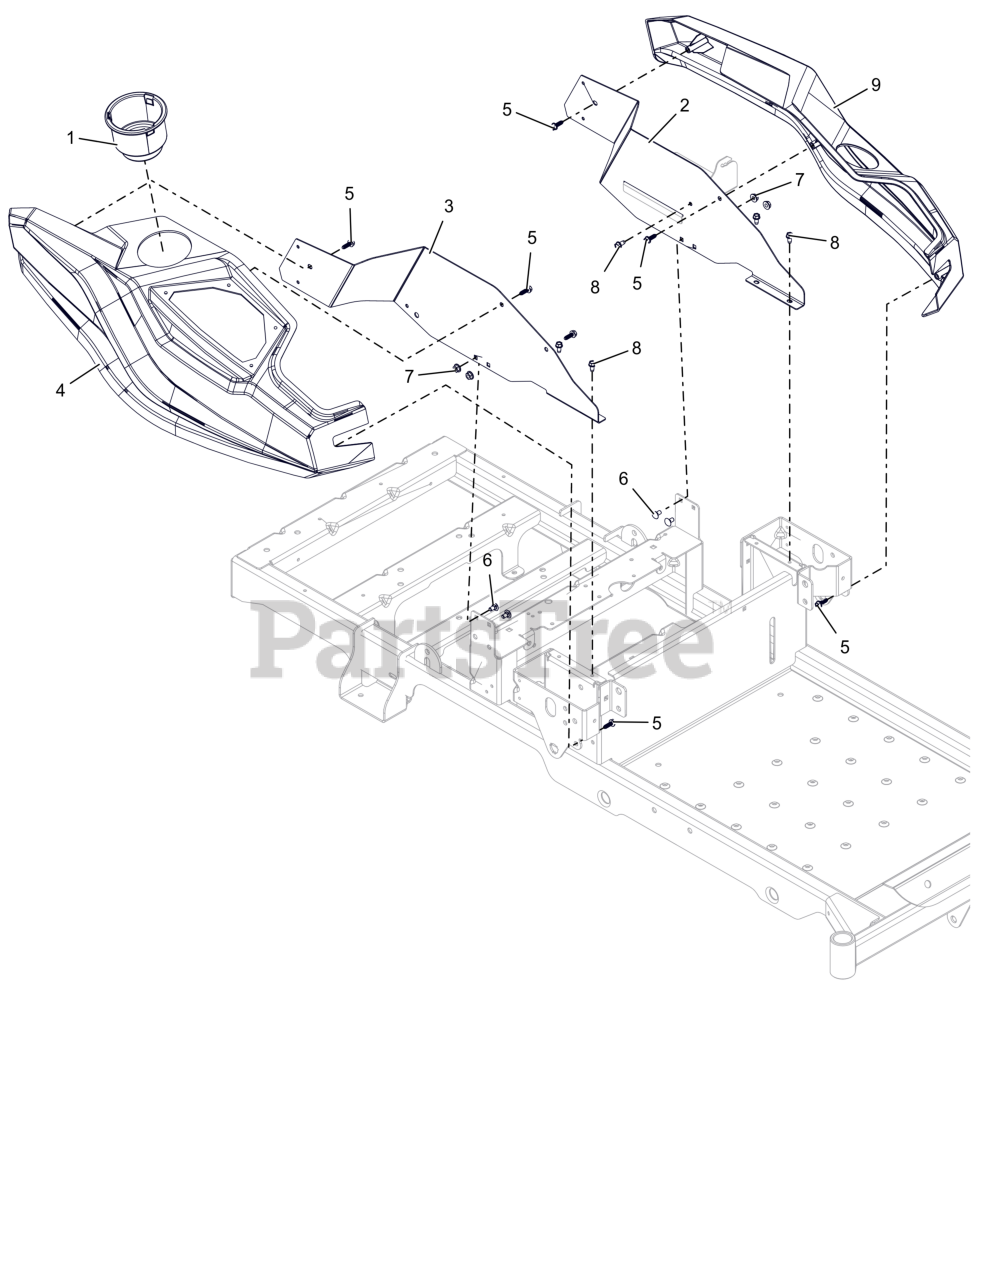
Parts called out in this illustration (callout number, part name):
1	CUPHOLDER, SNAP-IN 3.75OD
2	BRKT- FENDER MOUNTING LH
3	BRKT- FENDER MOUNTING RH
4	FENDER, RH
5	SCR, PLASTITE-HWH 0.25 X 0.75 ZC120
6	BLT, RHSN .25-20X.500 G5 ZCC
7	NUT-LK-CTR-FLG .25-20 ZC120
8	SCR-TAP .25-20X.50 HWH ZCC
9	KIT-FENDER WITH DECAL
